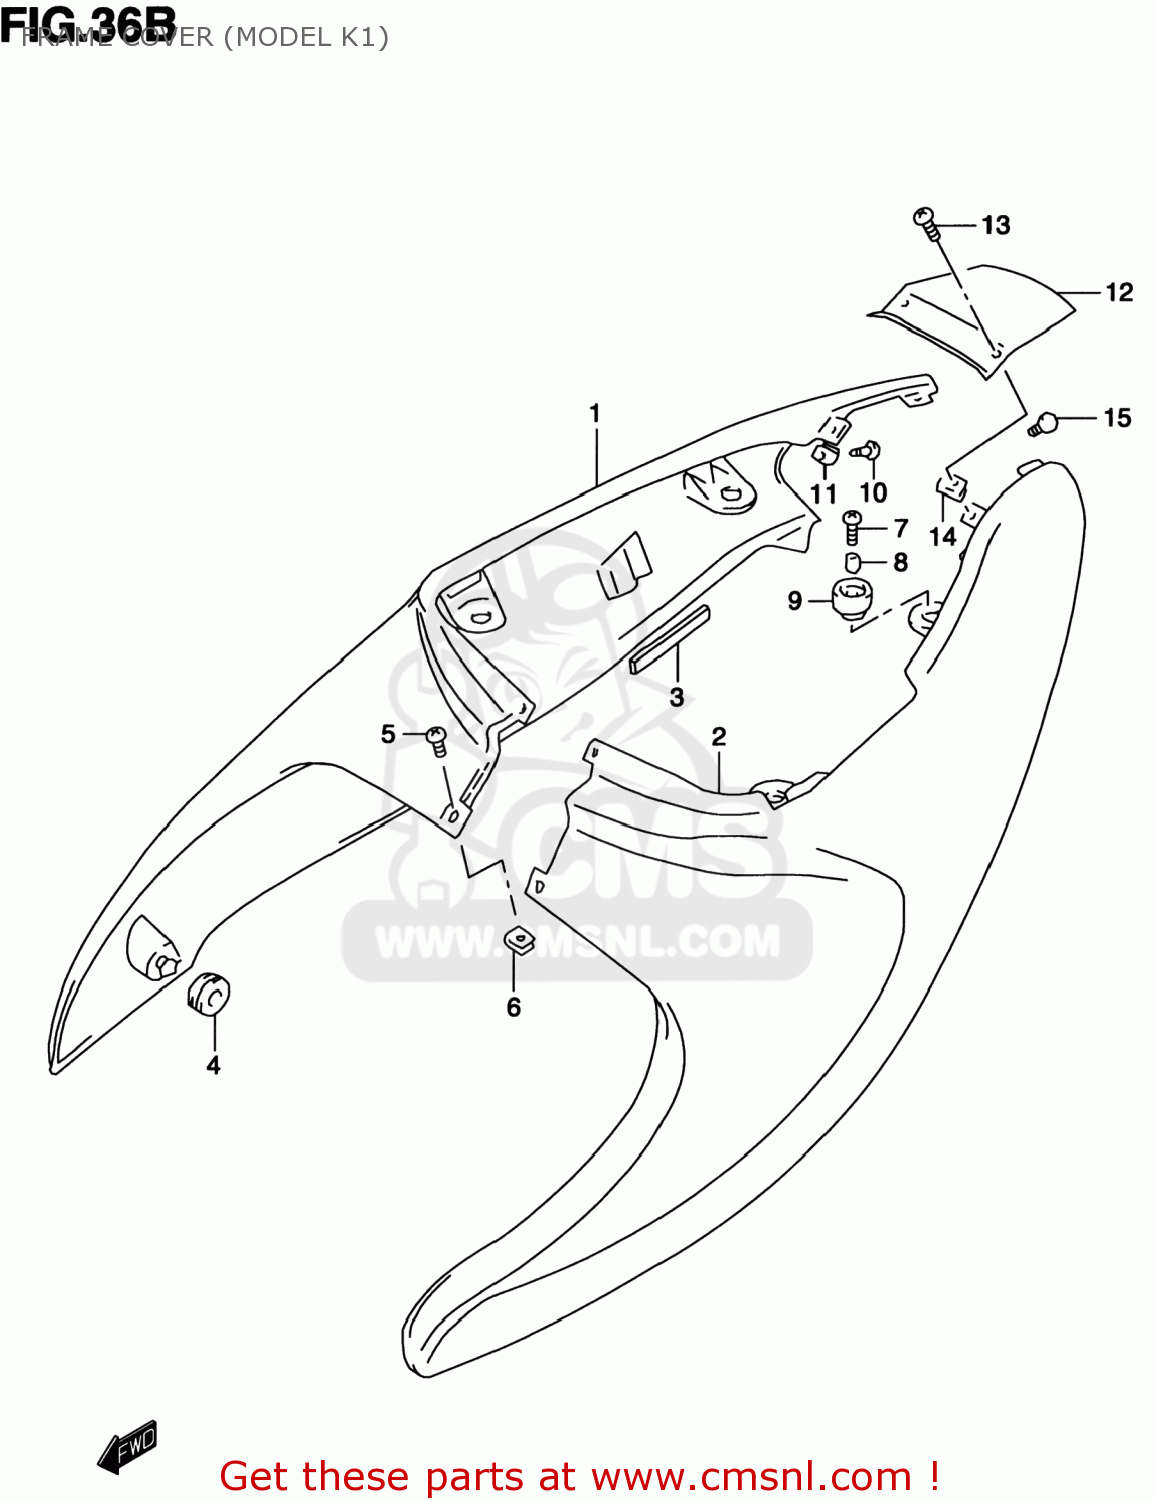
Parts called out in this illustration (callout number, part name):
1	COVER,FRAME,R(BLUE)
2	COVER,FRAME,L(BLUE)
3	CUSHION,FRAME COVER
4	CUSHION
5	SCREW
6	NUT
7	SCREW(6X20)
8	SPACER(6.5X10X9.4)
9	CUSHION
10	SCREW(5X16)
11	NUT
12	COVER,FRAME CTR
13	SCREW
14	NUT
15	CUSHION
